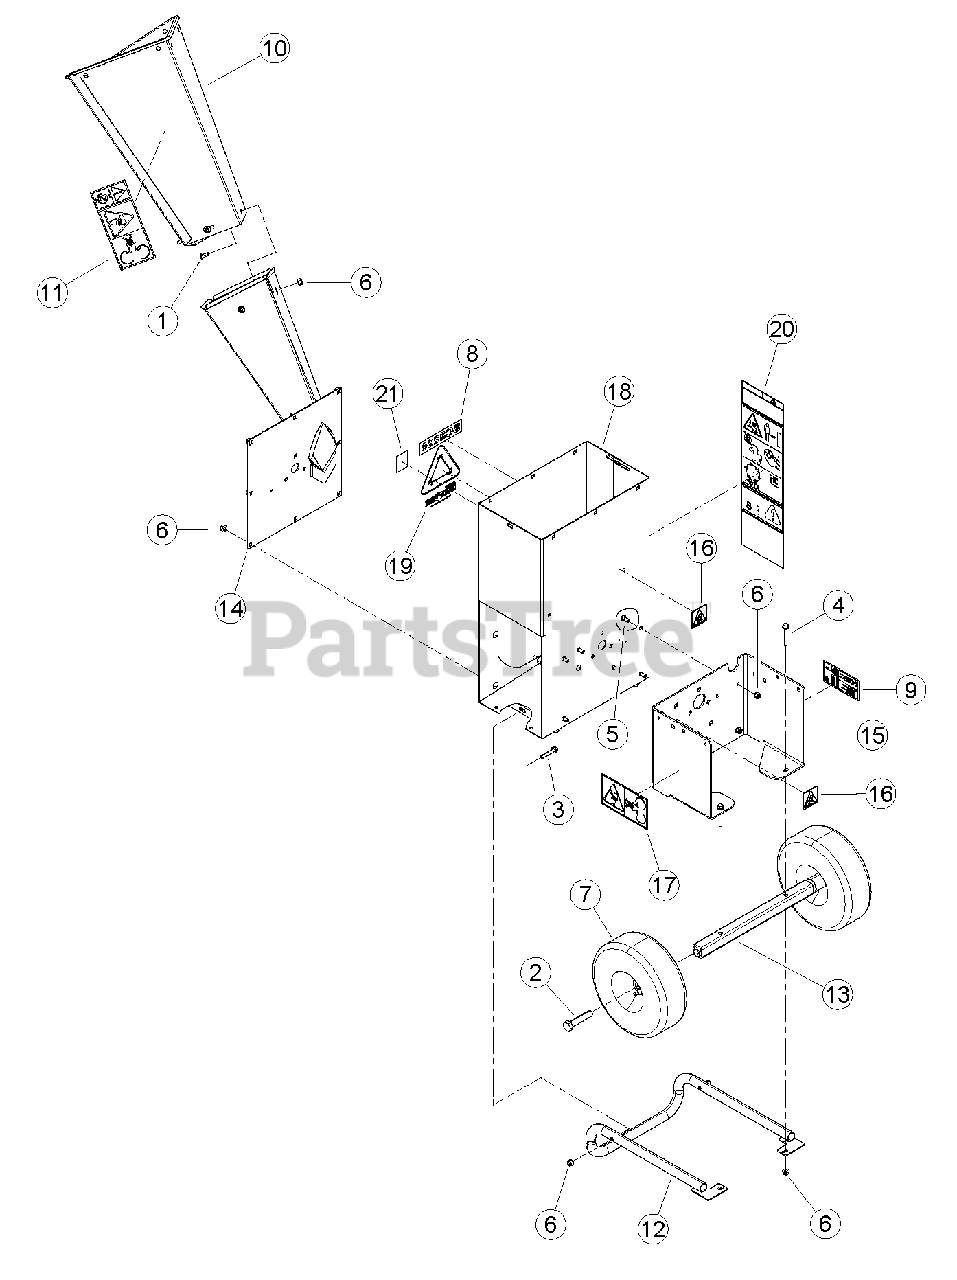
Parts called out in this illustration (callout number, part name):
1	BOLT, 5/16-18 X 3/4 CRG GR5 SN
2	BOLT, 5/8 X 3 HEX GR5 ZP
3	BOLT, 5/16 X 1-3/4 FLANGE NC
4	BOLT, 5/16 X 2-1/4 FLANGE NC
5	BOLT, 5/16 X 3/4 CRG GR5 NC ZP
6	NUT, 5/16-18 NYLOCK-FLANGE
7	ASSEMBLY, WHEEL 410/350-4
9	DECAL, SC3306 CE INFO AND NOISE
10	ASSEMBLY, 3" CHIPPER CHUTE EXTENSION
11	DECAL, 3" CHIPPER CHUTE
12	WELDMENT, SUPPORT LEG LONG
13	WELDMENT, AXLE 3 IN CHIPPER
14	WELDMENT, CHIPPER CHUTE
15	ASSEMBLY, BASE 3 IN CHIPPER SERVICE PART
16	DECAL, SHIELD DANGER ISO
17	DECAL, BLADE DANGER ISO
18	ASSEMBLY, 3" C/S WIDE BODY SERVICE PART
19	DECAL, SHRED IT
20	DECAL, 3" CHIPPER BODY SIDE
21	DECAL, ECHO BEARCAT QR CODE
